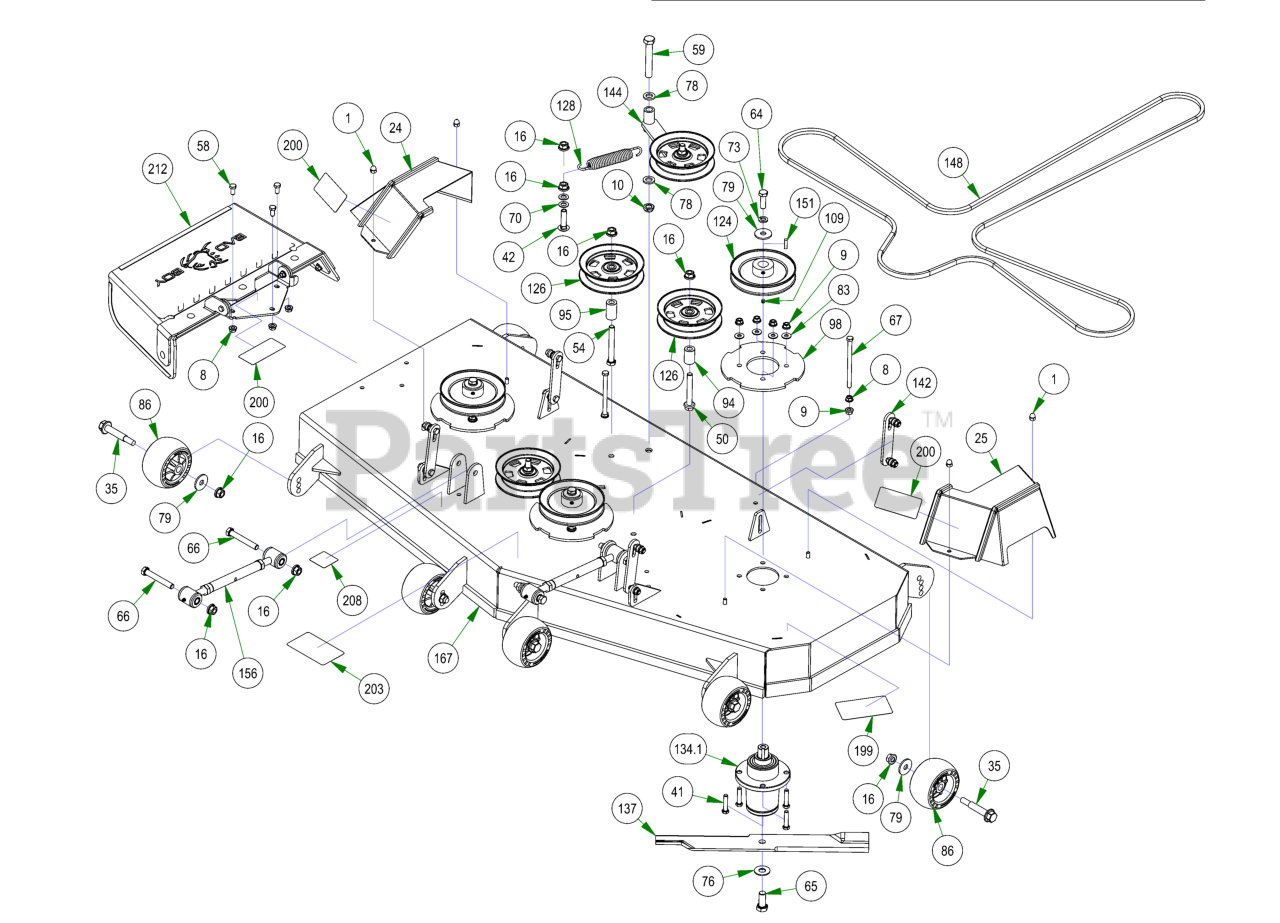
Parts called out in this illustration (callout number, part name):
1	5/16-18 ACORN NUT HIGH-CROWN ZC
8	3/8-16 HEX SERRATED FLANGE NUT HARD/ZINC
9	3/8-16 NYLON INSERT FLANGE LOCKNUT (GR.F) ZINC
10	5/8-11 NYLON INSERT JAM LOCKNUT ZINC
16	1/2-13 NYLON INSERT FLANGE LOCKNUT ZINC
24	2021 Maverick 54”/60” RH Pulley Cover
25	2021 Maverick 54”/60” LH Pulley Cover
35	Deck Wheel Bolt
41	3/8-16 X 1-3/4 HEX C/S (GR.5) ZC
42	1/2-13 X 2 CARRIAGE BOLT ZINC
50	1/2-13 X 3-1/2 HEX FLANGE BOLT (GR.8) ZINC
54	1/2-13 X 4 HEX CAP SCREW (GR.8) ZINC YELLOW
58	3/8-16 X 3/4 HEX CAP SCREW (GR.5) ZINC
59	5/8-11 X 4 HEX CAP SCREW (GR.8) ZINC YELLOW
64	1/2-20 X 1-1/2 HEX CAP SCREW (GR.5) ZINC
65	5/8-18 X 1-1/2 HEX CAP SCREW (GR.8) ZINC YELLOW
66	1/2-13 X 3-1/2 HEX CAP SCREW (GR.5) ZINC
67	3/8-16 X 5-1/2 HEX CAP SCREW (GR.5) ZINC
70	.517 SQ WDTH ID X .937 OD X .060 THICK F/W PHOS/OIL
73	1/2 SPLIT LOCKWASHER (GR.8) ZINC/YELLOW
76	5/8 USS FLAT WASHER (1-3/4" OD) GR.8 ZINC YELLOW
78	.635 ID X 1.120 OD X .140 THICK FLAT WASHER NYLON
79	1/2 BELLEVILLE WASHER (1-5/8 OD X .140 THK) ZINC
83	5/16 USS FLAT WASHER (7/8 OD) ZINC
86	Deck Wheel
94	.502 ID X .750 OD X 1.500 Long Spacer
95	1 3/4" Pulley Spacer
98	Deck Spindle Support Plate
109	5/16-24 X 1/4 SOCKET SET SCREW (CUP PT) PLAIN
124	6 1/4" Drive Pulley
126	5-3/4 Idler Pulley
128	Deck Idler Spring
134	Spindle Assembly
137	60" High Lift Fusion Blade
142	Deck Hanger Assembly
144	2017 MZ/ZT Deck Idler Assembly
151	1/4 X 1 SQ MACHINERY KEY 1018 STL PLN
156	2018 Maverick Turnbuckle (Top Link)
167	2017 60" ZT Deck Welded Assembly
199	2018 60" Deck Decal
200	Danger Decal-Spindle/Discharge
203	Deck Belt Route Decal
208	Deck Impact Patent Decal 9591803
212	Discharge Chute Assembly
